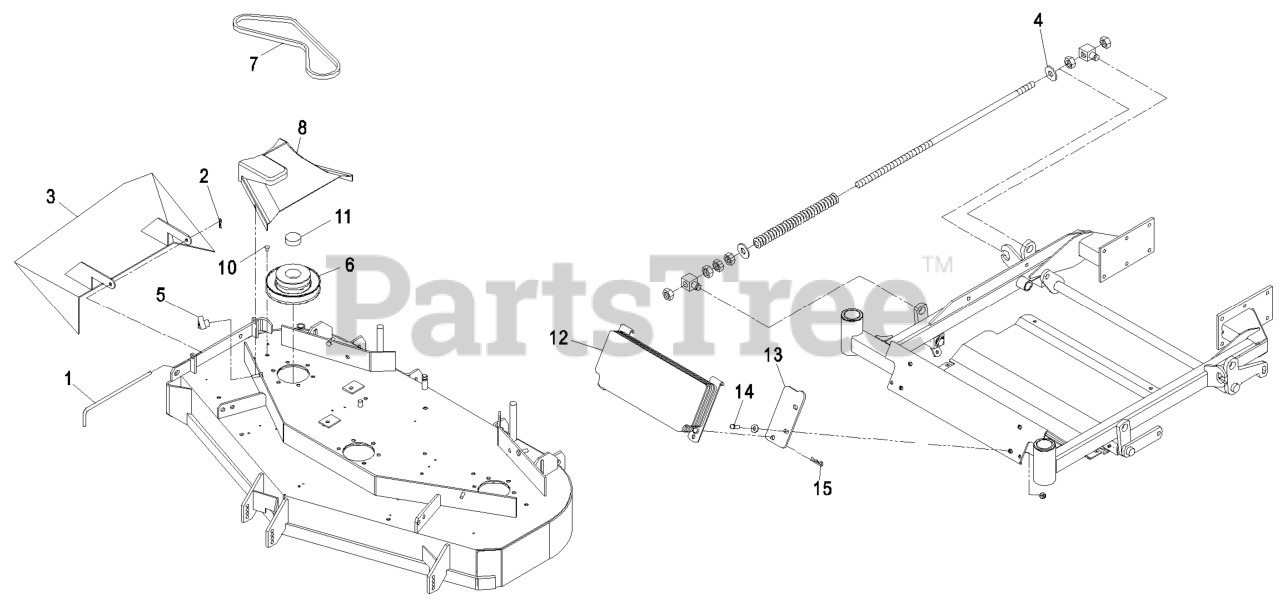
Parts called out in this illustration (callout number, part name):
1	PIN, CHUTE PIVOT PLTD
2	PIN-COTTER
3	Wld, Chute 48" Sd
4	Washer, 5/8 Type B Wide
5	KNOB-3 PRONG
6	SHEAVE, BLOWER DRIVE
7	BELT-BLOWER
8	COVER, BELT 44/48
9	Spacer, Counterweight
10	SCREW-HH
11	PLUG, BLACK NYLON 1.75
12	Asm, Weight (103-5608-01) W/Decals
13	PLATE-WEIGHT MOUNTING
14	SCREW-HH
15	Hairpin, Cotter
